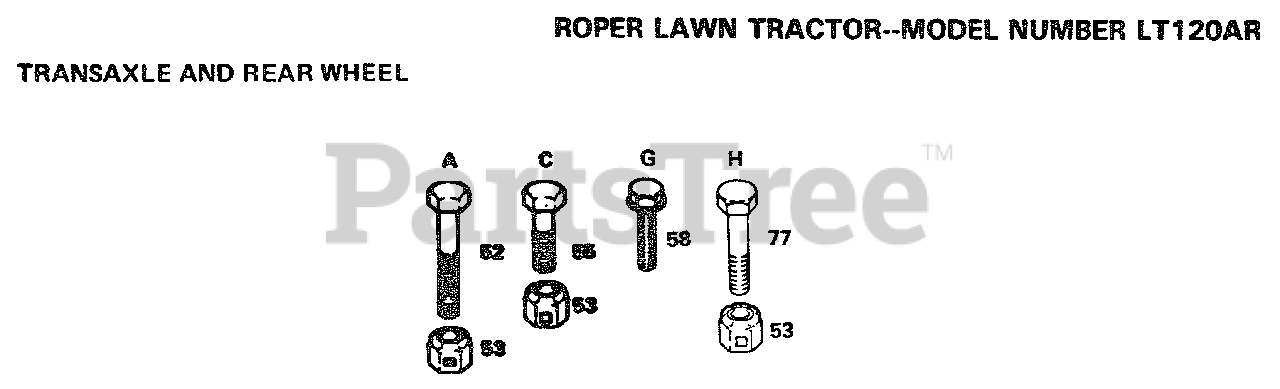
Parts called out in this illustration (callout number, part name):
52	BOLT
58	SCREW
77	BOLT
